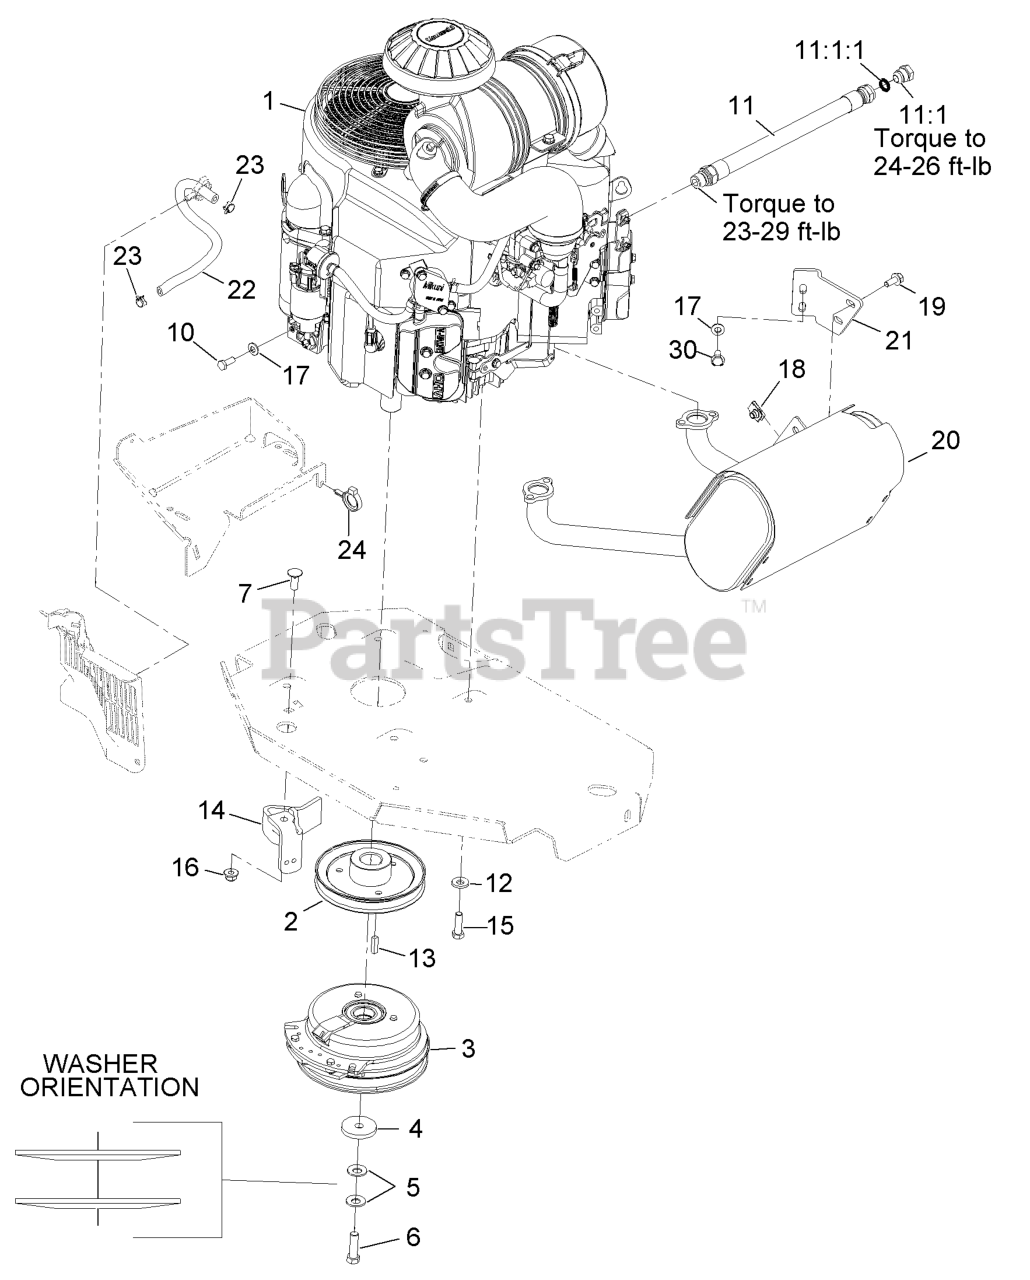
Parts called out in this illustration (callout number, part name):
2	SHEAVE
3	CLUTCH KIT
4	WASHER-CLUTCH
5	WASHER-SPRING
6	SCREW-HH 7/16-20 X 1 1/2 W/LOCTITE
7	SCREW-CARR
10	SCREW-HH
11	ENGINE OIL DRAIN HOSE ASM
11:1	PLUG-HH
11:1:1	O-RING
12	WASHER-BELLEVILLE
14	CLUTCH-ANCHOR
15	SCREW-HH
16	NUT-HF, NI
17	WASHER-SPRING
19	SCREW-HHF
20	MUFFLER
21	BRACKET-MUFFLER
22	HOSE-FUEL
23	CLAMP-HOSE
24	CLAMP-HOSE
30	SCREW-HHF
